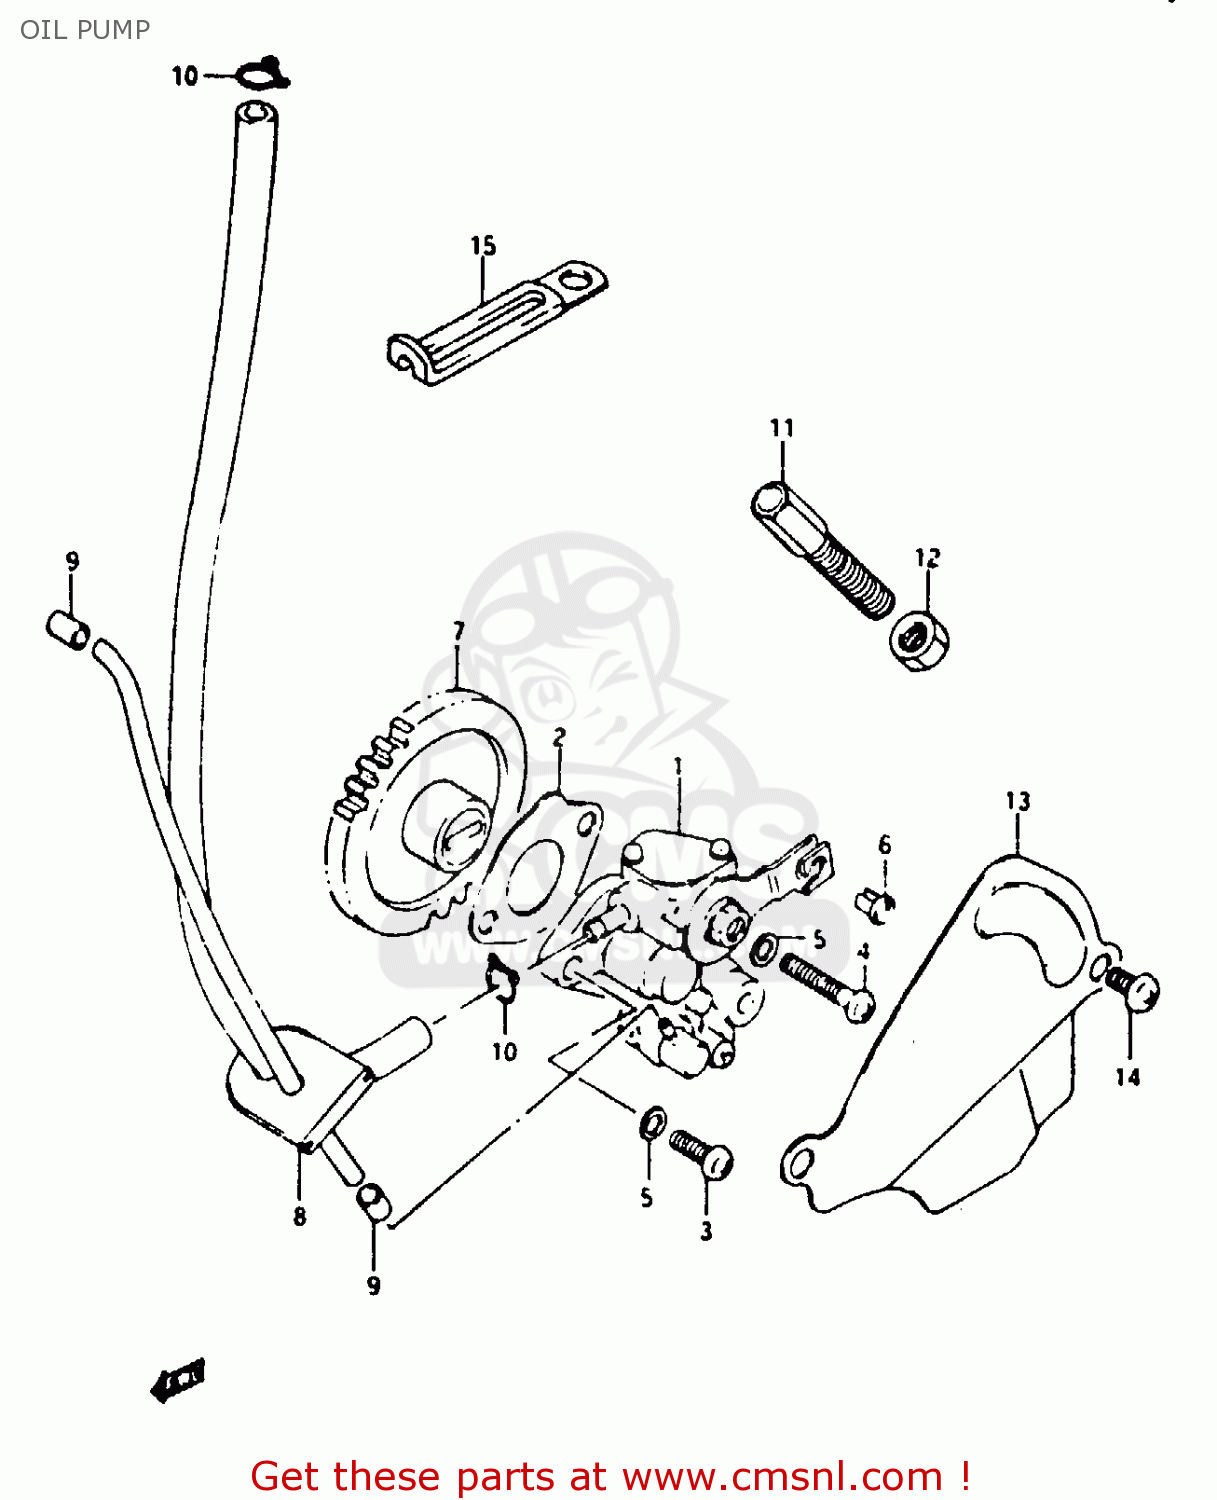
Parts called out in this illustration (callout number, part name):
1	PUMP ASSY, OIL
2	GASKET,OIL PUMP (NAS)
3	SCREW
4	SCREW
5	LOCK WASHER
6	TERMINAL,CABLE
7	GEAR, OIL PUMP DRIVEN (NT:29)
8	HOSE, OIL
9	CLIP
10	CLIP
11	BOLT
12	NUT
13	CAP, OIL PUMP INSPECTION
14	SCREW
15	CLAMP
